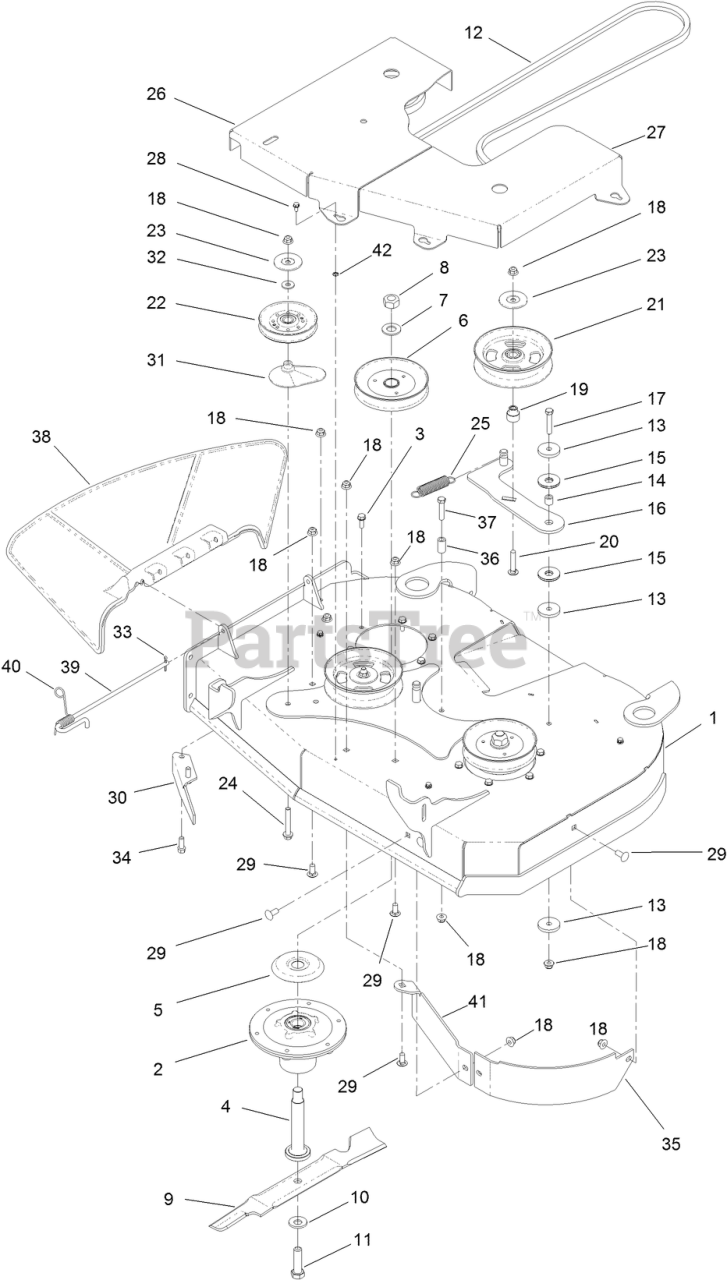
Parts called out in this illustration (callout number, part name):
1	36" DECK ASM-SERVICE
2	SPINDLE ASM
3	SCREW-TAPTITE
4	SHAFT-SPINDLE
5	SHIELD-BEARING
6	PULLEY
7	WASHER
8	NUT-HEX
9	BLADE - HI FLOW, 18.00 IN
10	WASHER-BELLEVILLE
11	SCREW-BLADE
12	BELT-V
13	WASHER-PLAIN
14	BUSHING-IDLER
15	WASHER-FRICTION, COMPOSITE
16	IDLER ARM ASM
17	SCREW-HH
18	NUT-HF, NI
19	BUSHING-IDLER
20	SCREW-CARR
21	PULLEY-IDLER, FLAT
22	IDLER - V 4.13 EOD-A
23	SHIELD-DUST
24	SCREW-HHF
25	SPRING-EXTENSION
26	COVER-DECK
27	COVER-DECK
28	SCREW-HWH
29	SCREW-CARR
30	BAFFLE-DISCHARGE
31	SPACER-PULLEY
32	WASHER-HARDENED
33	PIN-COTTER
36	SPACER-FENDER
37	SCREW-HH
38	DEFLECTOR-DISCHARGE
39	PIN-CHUTE
40	SPRING-TORSION
41	PLATE-DEFLECTOR
42	NUT-RETAINING
